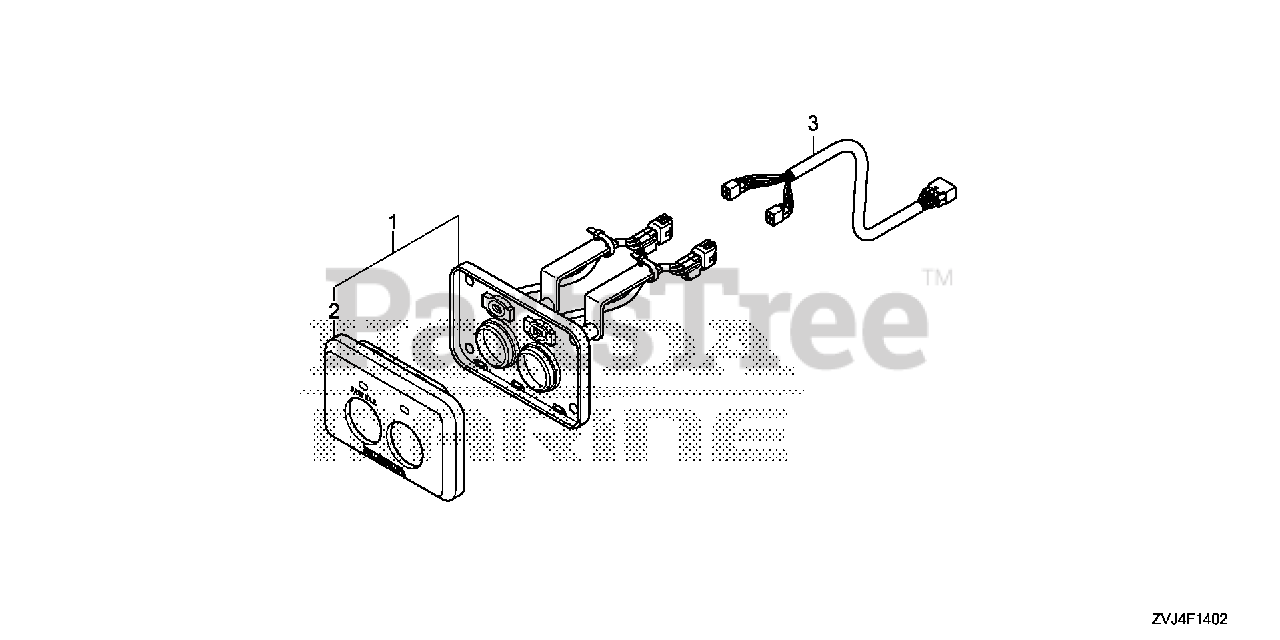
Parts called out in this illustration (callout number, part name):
1	PANEL ASSY., FUNCTION SWITCH
2	PANEL, FUNCTION SWITCH
3	SUB-HARNESS ASSY., FUNCTION SWITCH
